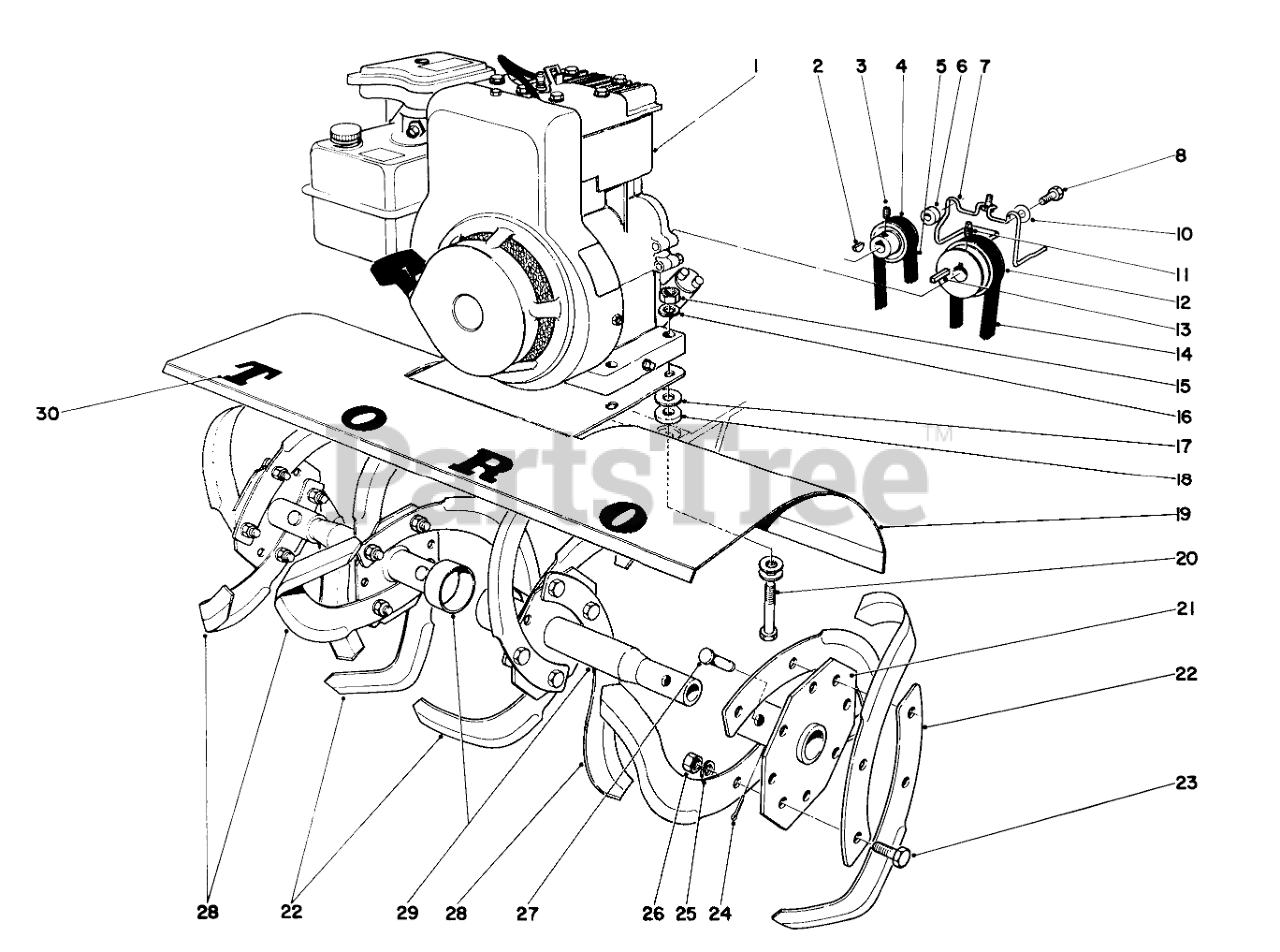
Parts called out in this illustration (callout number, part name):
1	Engine
2	KEY-WOODRUFF
3	SCREW-SET
4	Pulley
5	V-BELT
6	SPACER
7	Belt Guide
8	SCREW-HH
10	WASHER-FLAT
11	SCREW-SET, HSH
12	Engine Pulley
13	KEY-SQUARE
14	Belt
15	NUT-HEX
16	WASHER-LOCK
17	WASHER-FLAT
18	WASHER-FLAT
19	Shield
20	SCREW-HH
21	Axle Hub
22	RH TINE
23	SCREW-HH
24	PIN-COTTER
25	WASHER-LOCK
26	NUT-HEX
27	TINE PIN
28	LH TINE
29	Axle Hub
30	Decal
